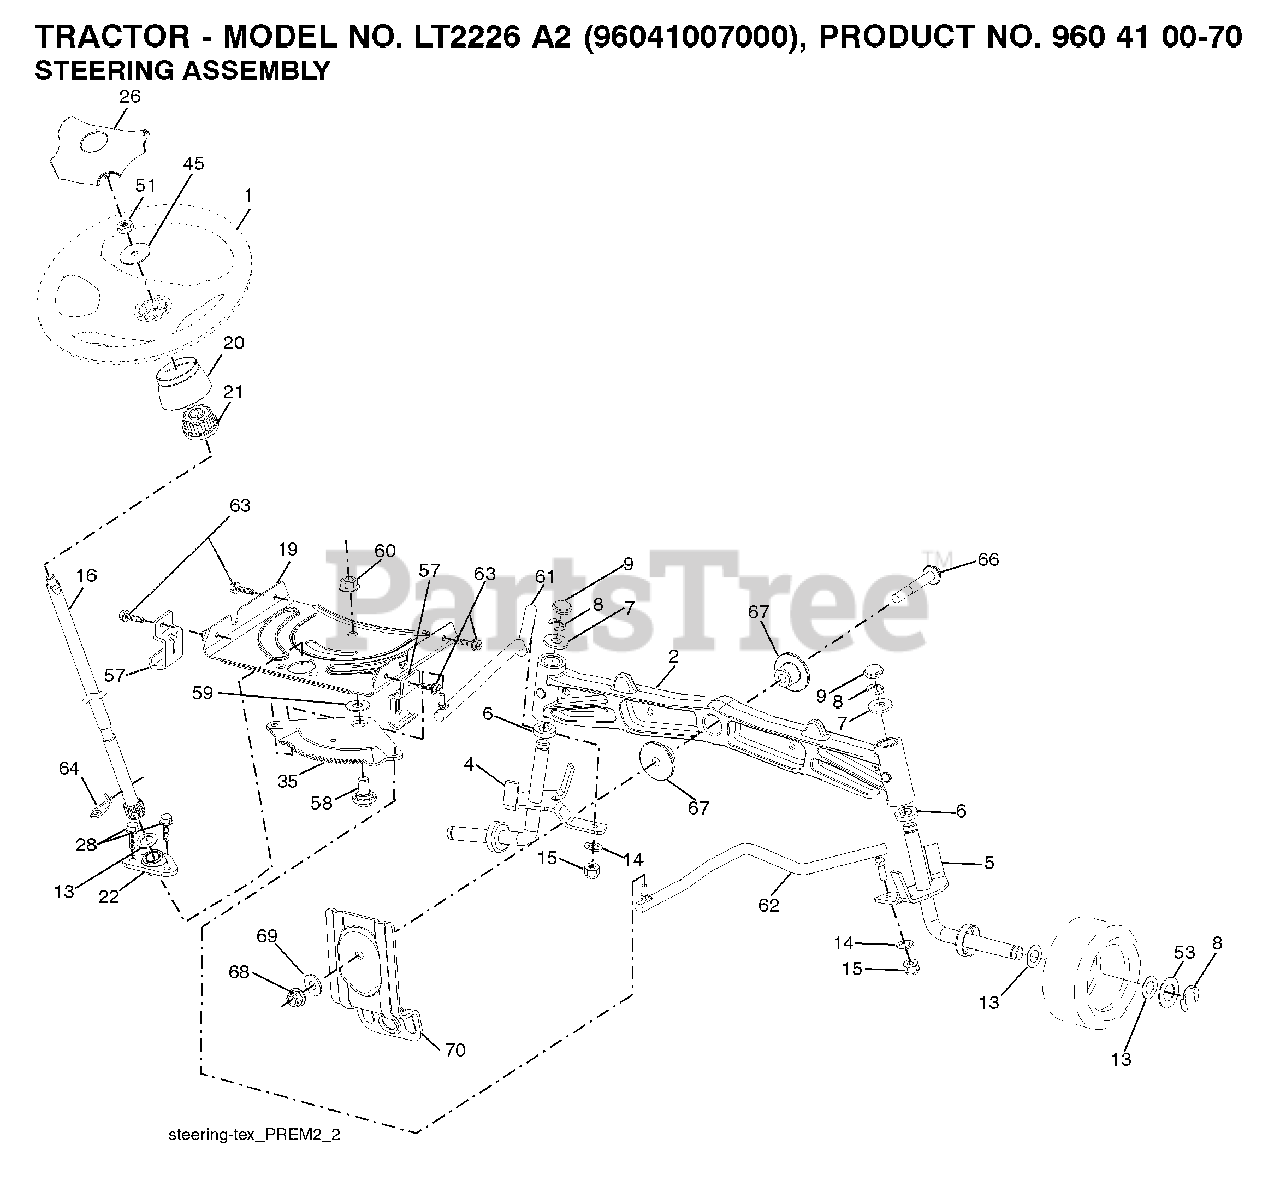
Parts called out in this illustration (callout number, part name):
1	WHEEL.STEERING.PREM.2.BLK
2	AXLE ASSY FRONT
4	SPINDLE.WELDED.LH.15"TEX
5	SPINDLE.WELDED.RH.15"T
8	RING CLIP
9	CAP.SPINDLE
14	WASHER, LOCK 3/8
15	NUT CROWNLOCK 3/8-24
16	SHAFT.STEER.STEALTH.DD
19	PLATE.STEER.DDL.NLT/NG
20	BOOT.STEERING.
21	ADAPTER, WHEEL STNG..
22	BUSHING.ASM.STEERING.A
26	INSERT.CAP.STRG.WH.BLACK
28	SCREW, 3/8-16X3/4
35	GEAR.SECTOR.PLATE.DDL.
45	WASHER.11/32
51	NUT.HEX.1/2-20
53	WASHER.HARDENED
57	BRACKET.UPSTOP.TEX
58	BOLT.SHOULDER.SECTOR.P
59	WASHER.THURST.SECTOR.S
60	NUT FLANGE LOCK 5/8-11
61	DRAGLINK.LH.BALLSTUD.D
62	DRAGLINK.RH.BALLSTUD.D
63	SCREW
64	RETAINER.CLIP.SPRING.S
66	BOLT HEX FGHD 7/16-14 X 3 SERR
67	BUSHING.PM.FRONT AXLE
68	NUT.LOCK.FLANGE.7/16
69	WASHER.1.5X.505X.118
70	BRKT.DECK.SUSPENSION.F
